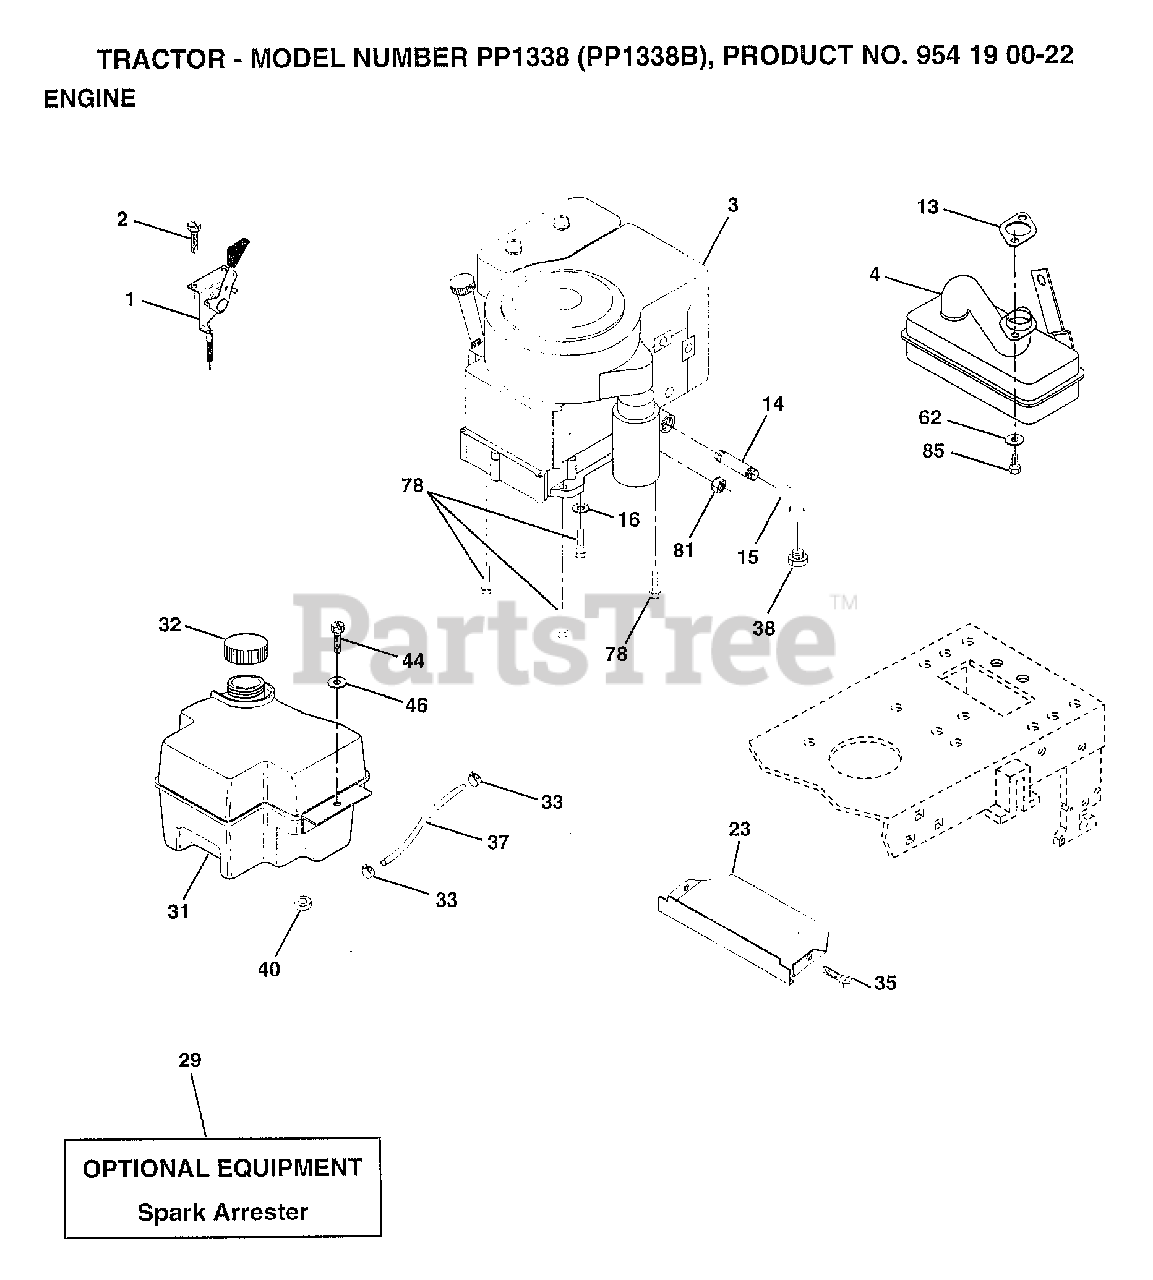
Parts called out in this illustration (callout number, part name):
1	CONTROL-THROT/CHO
2	SCREW LT
4	MUFFLER TEC. 13HP
13	GASKET ENG 1 313 LD TIN PLATED
14	PIPE NIPPLE LT
15	ELBOW
16	LOCKWASHER
23	SHIELD.BRN/DBR.GD
31	TANK.FUEL.FRONT.
32	CAP ASM FUEL
33	HOSE CLAMP
35	SCREW
37	LINE FUEL
44	SCREW HEX CRT
46	WASHER
62	LOCKWASHER
78	SCREW
81	NUT
85	SCREW HEX HD CAP
